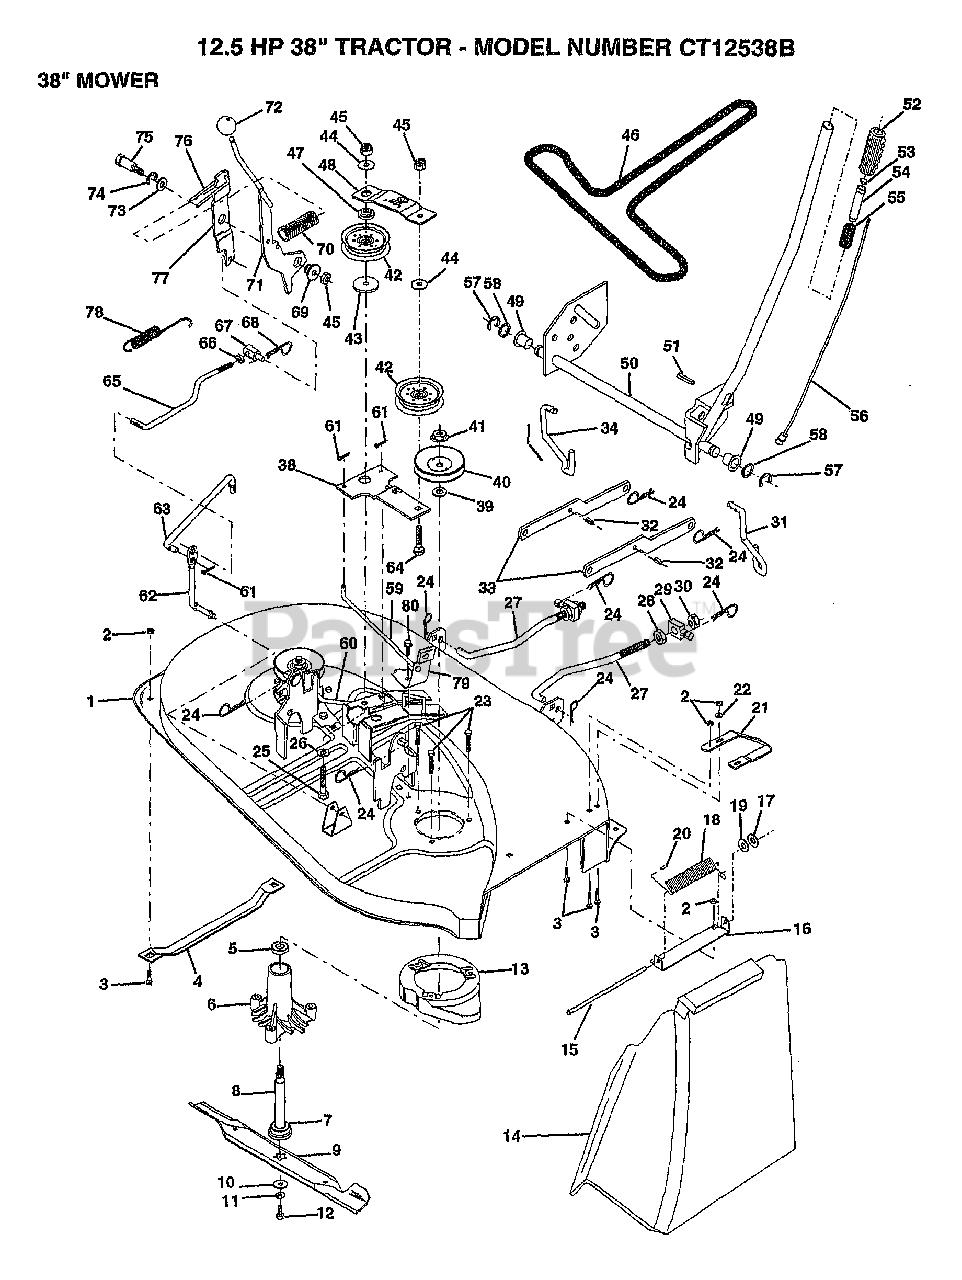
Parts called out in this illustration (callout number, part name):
3	BOLT
4	RUNNER-LH M
5	BEARING
6	HSG ASM MANDREL
7	BEARING.BALL
10	WASHER BLADE
12	BLADE BOLT
14	DEFLECTOR-SHLD T
15	ROD-HINGE T
17	NUT PUSH M
19	WASHER
20	CAP-SLEEVE LT
21	RUNNER RH
22	WASHER M
25	BOLT
26	WASHER GT
27	LINK.FRONT
28	NUT
29	TRUNION
30	NUT.LK.W/WSH.1/2.
31	LIFT LINK RH
32	"PIN,SPRING"
33	SUSP ARM ASM REAR
34	LINK LIFT LH
38	IDLER ARM ASSY
39	WASHER
42	FLAT IDLER PULLEY
43	SPACER RETAINER
44	WASHER GT
46	BELT-V.88.12.MW
47	RETAINER SPACER
48	IDLER ARM STIFF
49	NYLON BEARING
51	PIN-GROOVE LT
52	GRIP
58	WASHER
59	BRAKE ROD RH
60	BRAKE ROD LH
62	PIVOT ROD
63	CLUTCH ROD SECOND
64	BOLT
66	NUT
67	TRUNION
68	RETAINER M
69	BUSHING
71	CLUTCH ARM PRI AS
72	KNOB T(3/8 HOLE)
73	WASHER
74	RING
75	SHOULDER BOLT
76	SPRING KEEPER
77	CLUTCH ARM SECOND
78	RETURN SPRING
79	BRAKE ASM
80	SCREW
